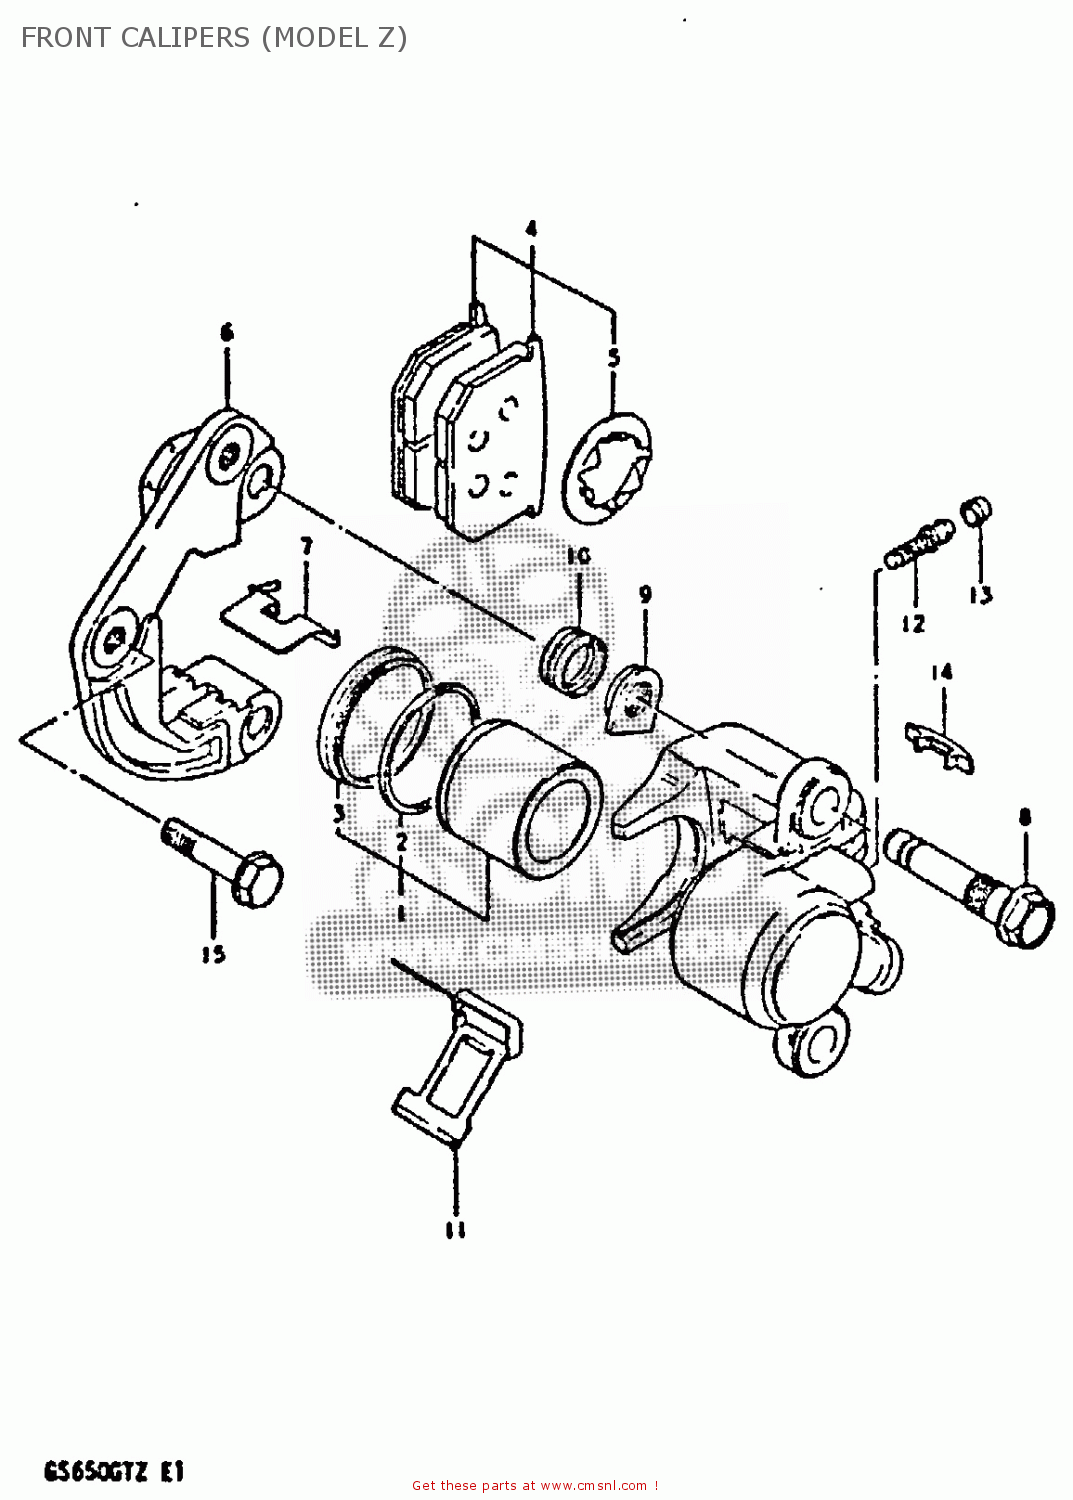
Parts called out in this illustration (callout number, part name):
1	PISTON SET
2	SEAL,PISTON
3	BOOT,PISTON
4	PAD & SHIM SET (MCA)
5	SHIM,PAD
6	HOLDER,CALIPER,LEFT
7	PAD,GUIDE
8	AXLE,CALIPER
9	NUT,CALIPER AXLE
10	BOOT
11	SPRING
12	BREATHER
13	CAP,BLEEDER PL
14	COVER,INDICATOR
15	BOLT(10X37)
